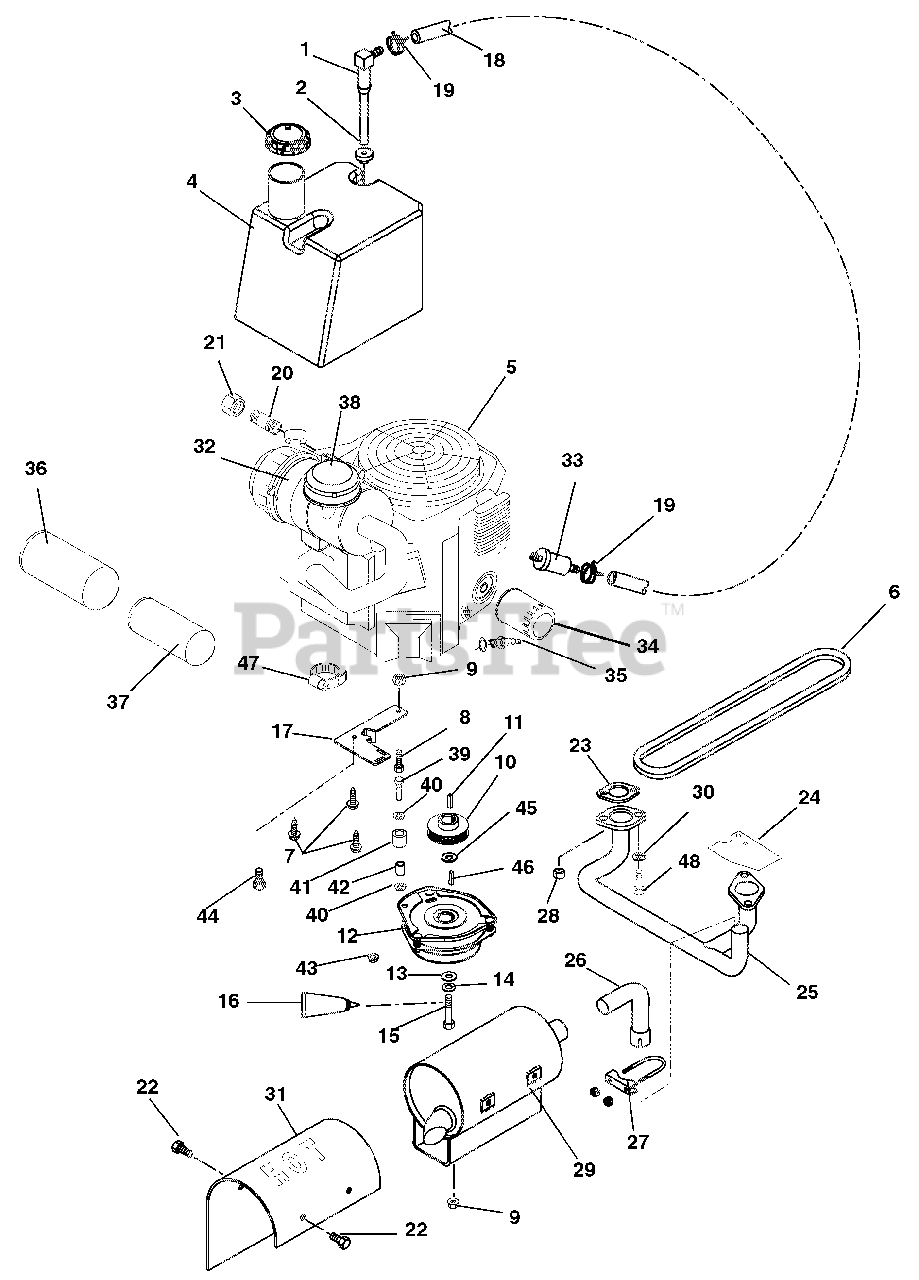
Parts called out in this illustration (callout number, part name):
1	Fitting, Tank
3	Cap, Gas
4	Tank, Fuel
5	Engine, 27HP Kohler 6-Pin (021)
6	Belt, HA 59.80 Raw Laminated
7	Screw, Tapping Hex-Washer-Head .38-16 x 1.00 (021)
8	Bolt, Hex .31-18 x 1.75 Grade 5 (021)
9	Nut, Locking-Top-Flange .31-18 (021)
10	Pulley, 4.46 Dia. x 1.12 Bore
11	Key, Square .25 x 1.00 x .25
12	Clutch, Electric-OGURA GT3.5-VP01R
13	Washer, Flat-Steel .469 x 2.00 x .25
14	Washer, Locking .44 x .109
15	Bolt, Hex .44-20 x 1.50 Grade 5 EP80 (023)
16	Loc-Tite™ 271 (Red)
17	Anchor, Clutch
18	Gas Line-Bulk 1/4" ID (021)
19	Hose, Clamp
20	Nipple, Pipe .38 x 6.00 Unfinished Steel
21	Pipe Cap
22	Bolt, Hex M5 -.8 x 8 mm
23	Gasket, Exhaust
24	Heat Deflector (021)
25	Manifold-Kohler CV18-27 (021)
26	Tube, Manifold
27	U-Bolt, 1/4-20 x 1.50
28	Nut, Locking-Top M8-1.25 (021)
29	Muffler (Includes 09066300 Heat Shield)
30	Washer, Locking .31 x .078 (023)
31	Heat Shield (Included with 09065600 Muffler)
32	Air Cleaner Assembly (021)
33	Fuel Filter (021)
34	Filter, Oil- Kohler CV20 (021)
35	Spark Plug (021)
36	Element, Outer Primary
37	Element, Inner Safety
38	Cap, 2" Air Cleaner Intake (021)
39	Bolt, Hex .38-16 x 1.50 Grade 5
40	Washer, Flat-Steel .406 x .812 x .065
41	Bumper, Rubber .62 x 1.0 x .88 LG
42	Bushing, S.407 x .625 x .813 Steel
43	Nut, Locking Top Flange .38-16
44	Bolt, Hex .38-16 x 1.25 Grade 5 EP30 (023)
45	Washer, Thrust 1.125 x 1.750 x .1245
46	Key, Square .25 x 2.50 x .25
47	Clamp, Hose 2.75 Diameter Worm (023)
48	Screw, Socket Head M8 x 1.25 x 20
